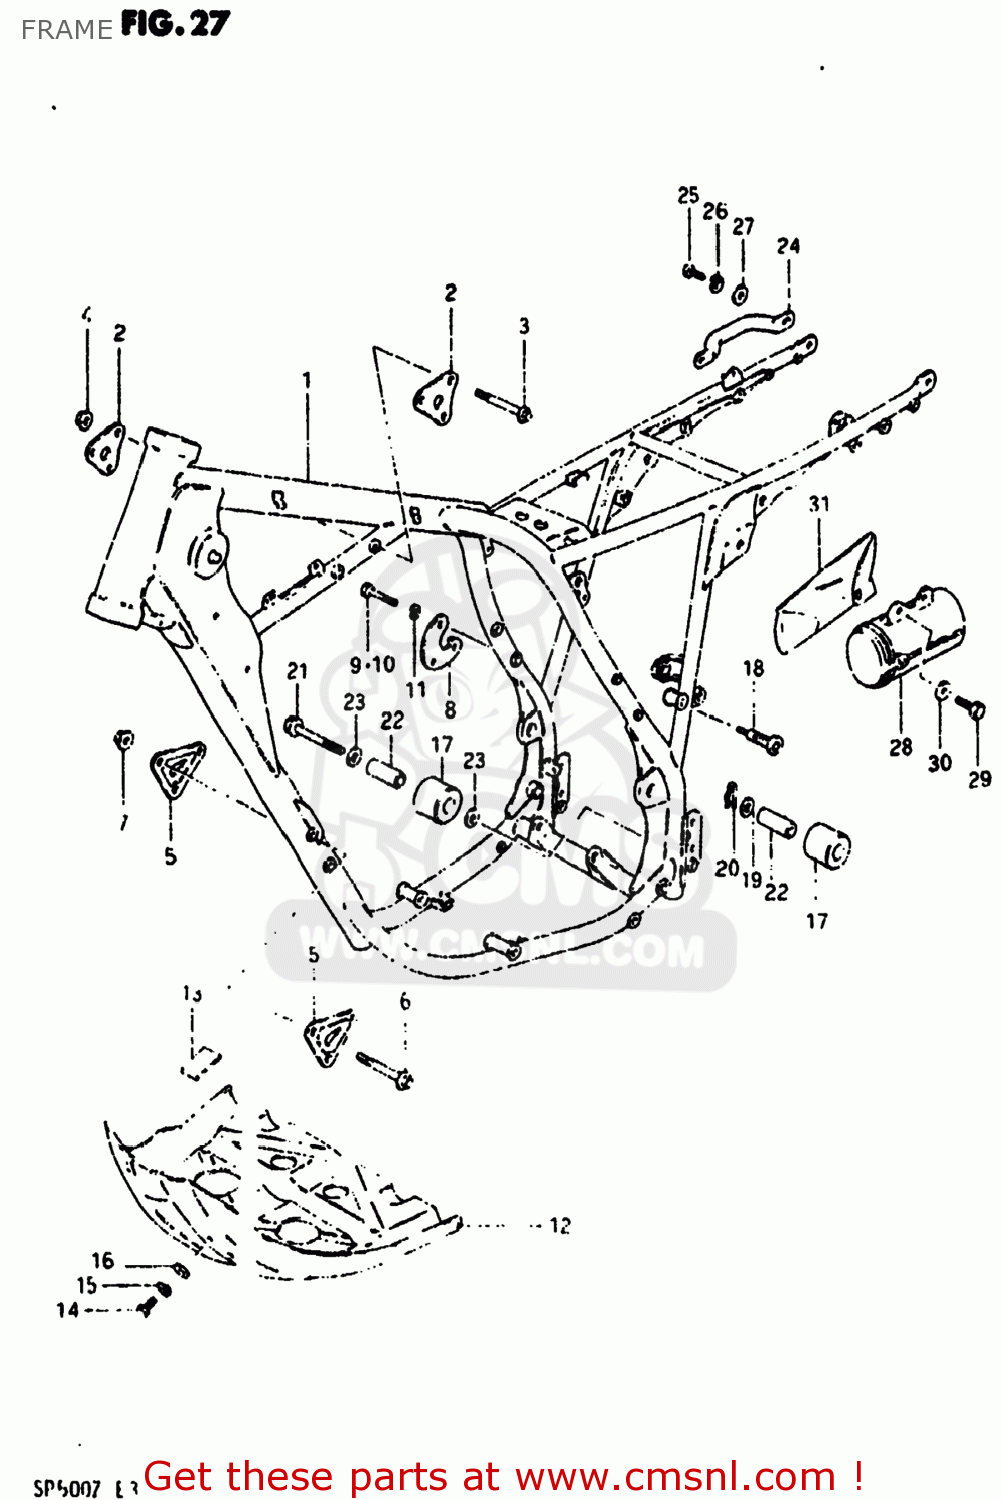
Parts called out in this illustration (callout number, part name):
1	FRAME
2	PLATE,ENGINE MOUNTING,UPPER
3	BOLT
4	NUT
5	PLATE,ENGINE MOUNTING,FRONT
6	BOLT
7	NUT
8	PLATE,ENGINE MOUNTING
9	BOLT
10	BOLT 8X50
11	LOCK WASHER
12	PLATE,ENGINE,UNDER
13	CUSHION,ENGINE,UNDER
14	BOLT
15	LOCK WASHER
16	WASHER
17	ROLLER,CHAIN LENGTH CONTROL
18	BOLT,CHAIN LENGTH ROLLER
19	WASHER
20	E RING 8MM
21	BOLT(8X45)
22	SPACER,CHAIN LENGTH ROLLER
23	WASHER
24	GRIP,FRAME HANDLE
25	BOLT
26	LOCK WASHER
27	WASHER
28	HOLDER,TOOL
29	BOLT, UPPER
30	WASHER
31	TOOL SET
